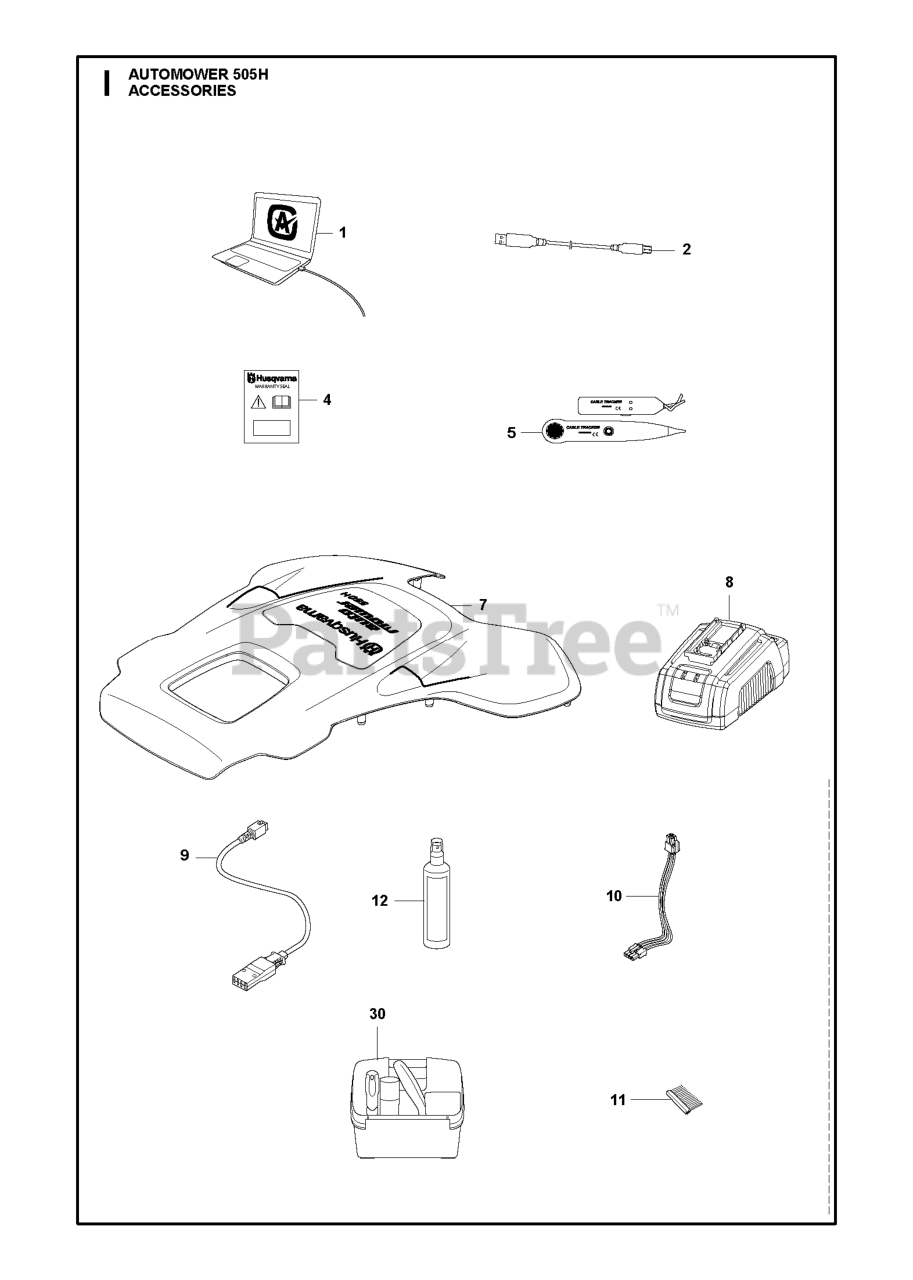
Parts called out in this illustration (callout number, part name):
2	CABLE WHITE ALT GREY
4	LABEL WARRANTY SEAL DEALER
5	TEST EQUIPMENT
7	Body
7	BODY KIT SPARE PART TOP COVER
8	CHARGER BATTERY TEST
9	CABLE ASSY QUICK CHARGER
10	WIRING ASSY BATTERY CABLE
11	WHEEL BRUSH REFILL KIT
12	AUTOMOWER ACCY
13	COVER
14	DECAL
16	HANDLE RELEASE LEFT
17	ROD
18	SPRING SPRING CAP
19	HINGE PIN
20	BEAM
21	SCREW 14MM
22	HANDLE RELEASE RIGHT
23	HATCH
25	Screws
26	SUPPORT BASE LEFT
27	NUT
28	SUPPORT BASE RIGHT
29	SCREW IHPANM M6X25 4.6 ZP-BC
30	CLEANING AND MAITENANCE KIT AM
31	HANGER
